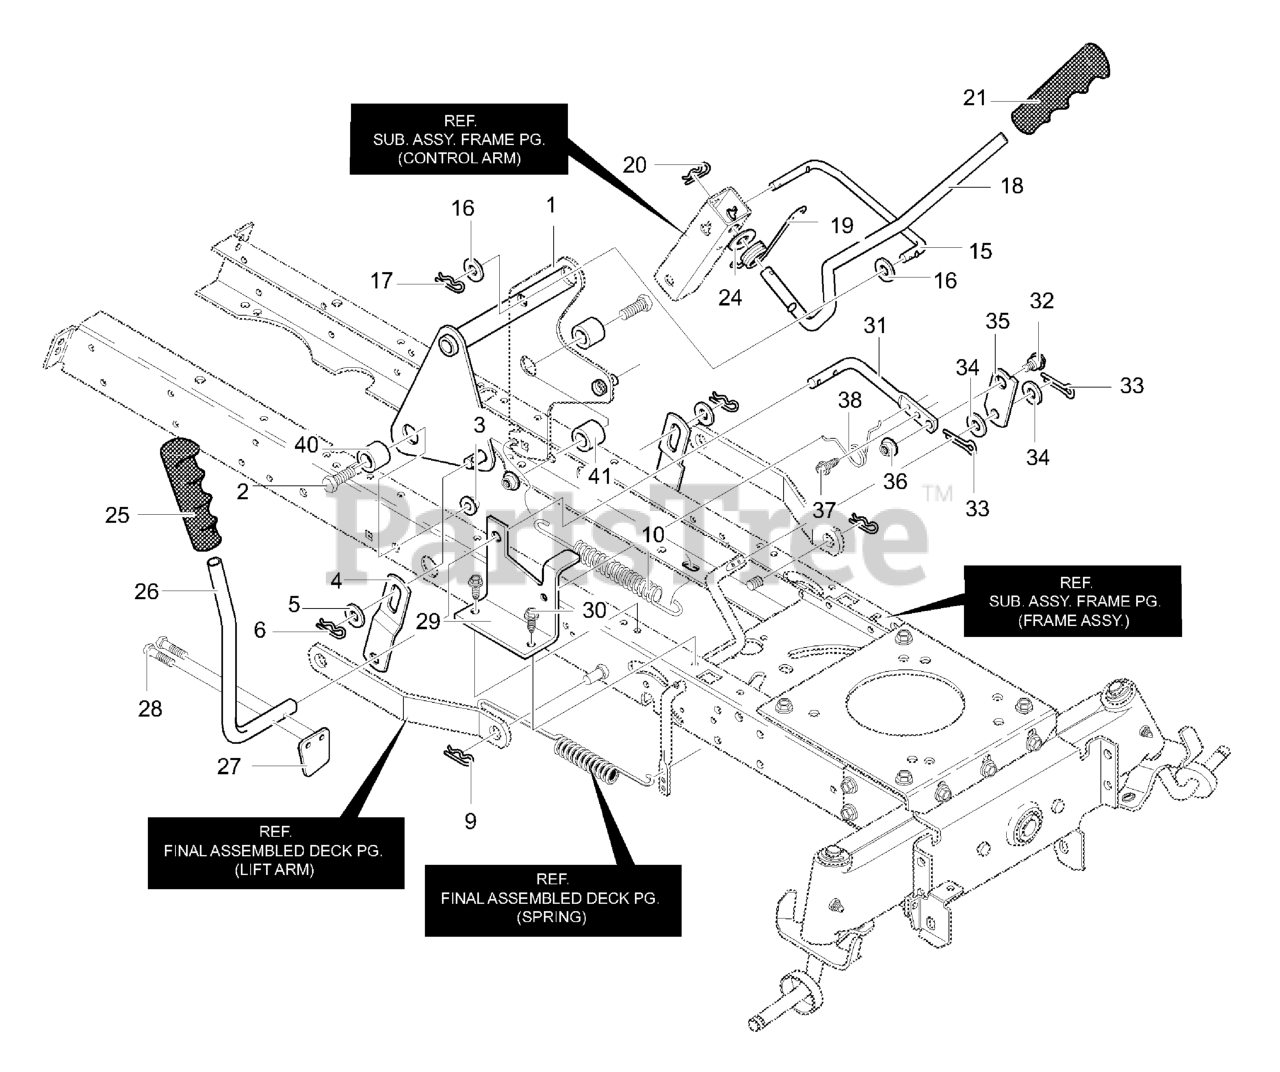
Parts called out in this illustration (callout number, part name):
1	Assembly, Lift Arm
2	Screw, 1/2-13x1.50
3	Nut, 1/2-13 Lock
4	Bracket. Lift Link
5	Washer, Flat
6	Hair Pin
9	Hair Pin
10	Spring, Extension
15	Link-Lift Handle
16	Washer, Flat
17	Hair Pin
18	Handle, Lift
19	Torsion Spring
20	Hair Pin
21	Grip, Lift
24	Washer, Flat
25	Grip, PTO
26	PTO Handle
27	Paddle, Switch
28	Screw, Thread Form
29	Bracket, PTO
30	Screw, 5/16-18 x 0.50
31	Lever, PTO
32	Bolt, Shoulder 3/8-16
33	Hair Pin
34	Washer, Flat
35	Link PTO
36	Nut, 3/8-16
37	Screw 5/16-18x.75
38	Torsion Spring
40	Spacer
41	Spacer, Sleeve
